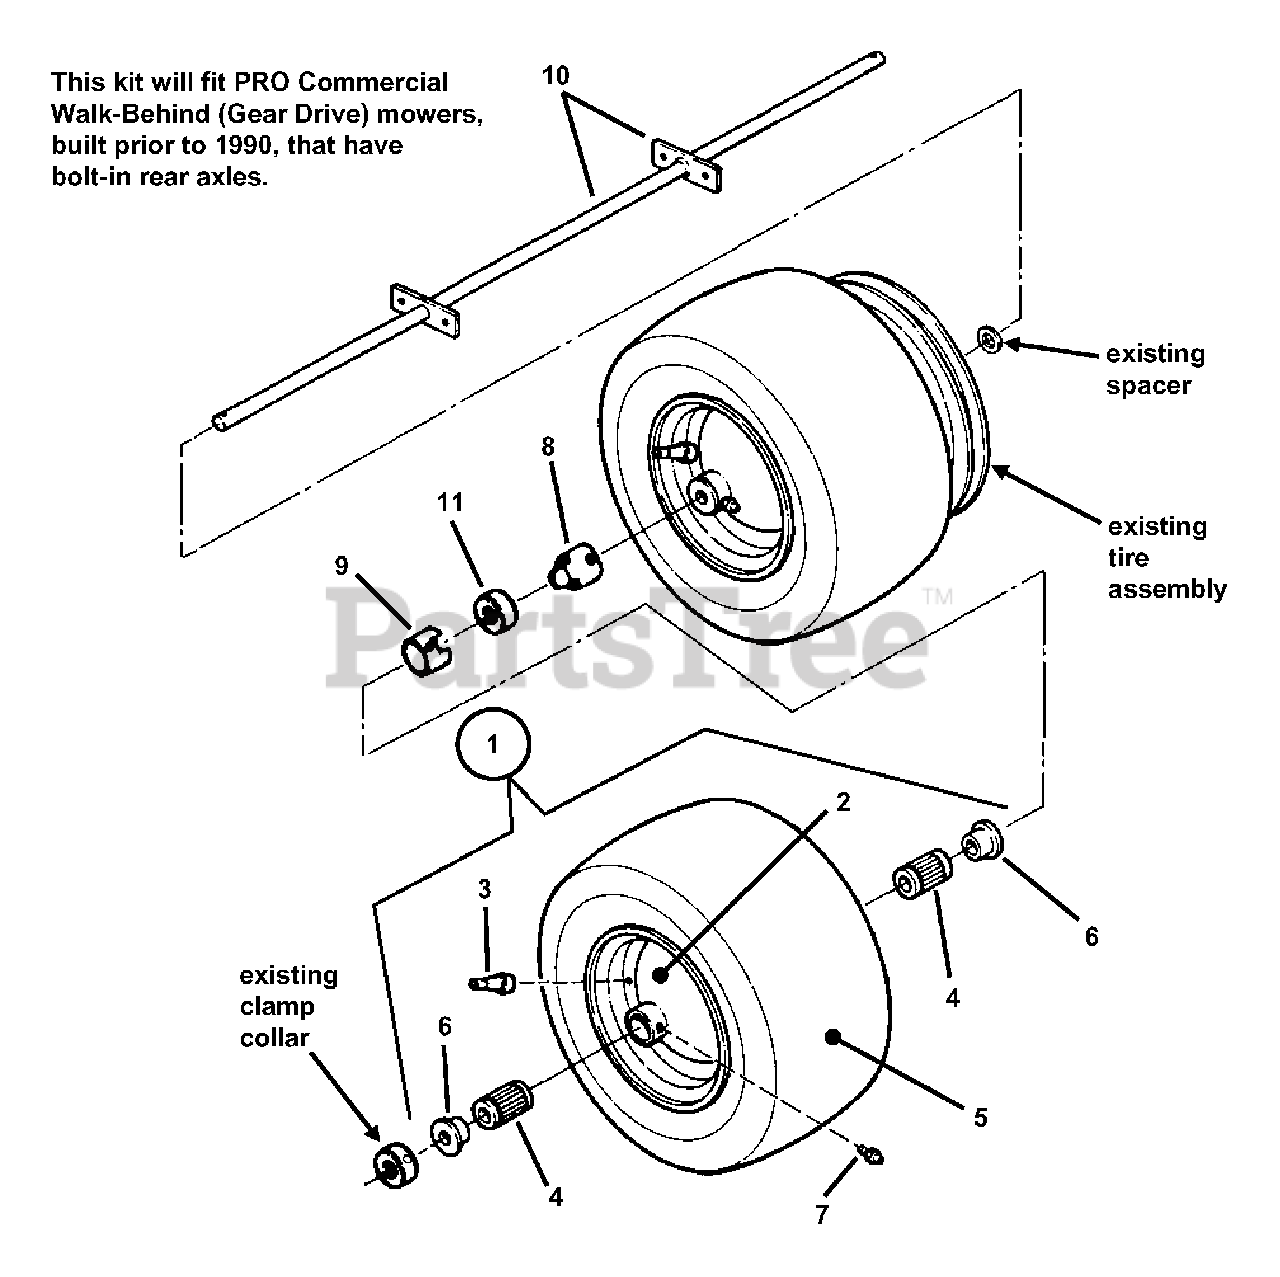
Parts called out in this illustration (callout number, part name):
1	ASSEMBLY, Sulky Tire (complete)
2	RIM
3	STEM, Air Valve
4	BEARING, Roller
5	TIRE, 13 x 6.50-6
6	BEARING, Flange
7	FITTING, Lube, 1/4-28, Straight
8	COUPLING-DRIVE, Inside
9	COUPLING, Drive, Outside
10	WELDMENT, Rear Axle, Dual Wheel, PTD
11	SPACER, Dual Wheel
